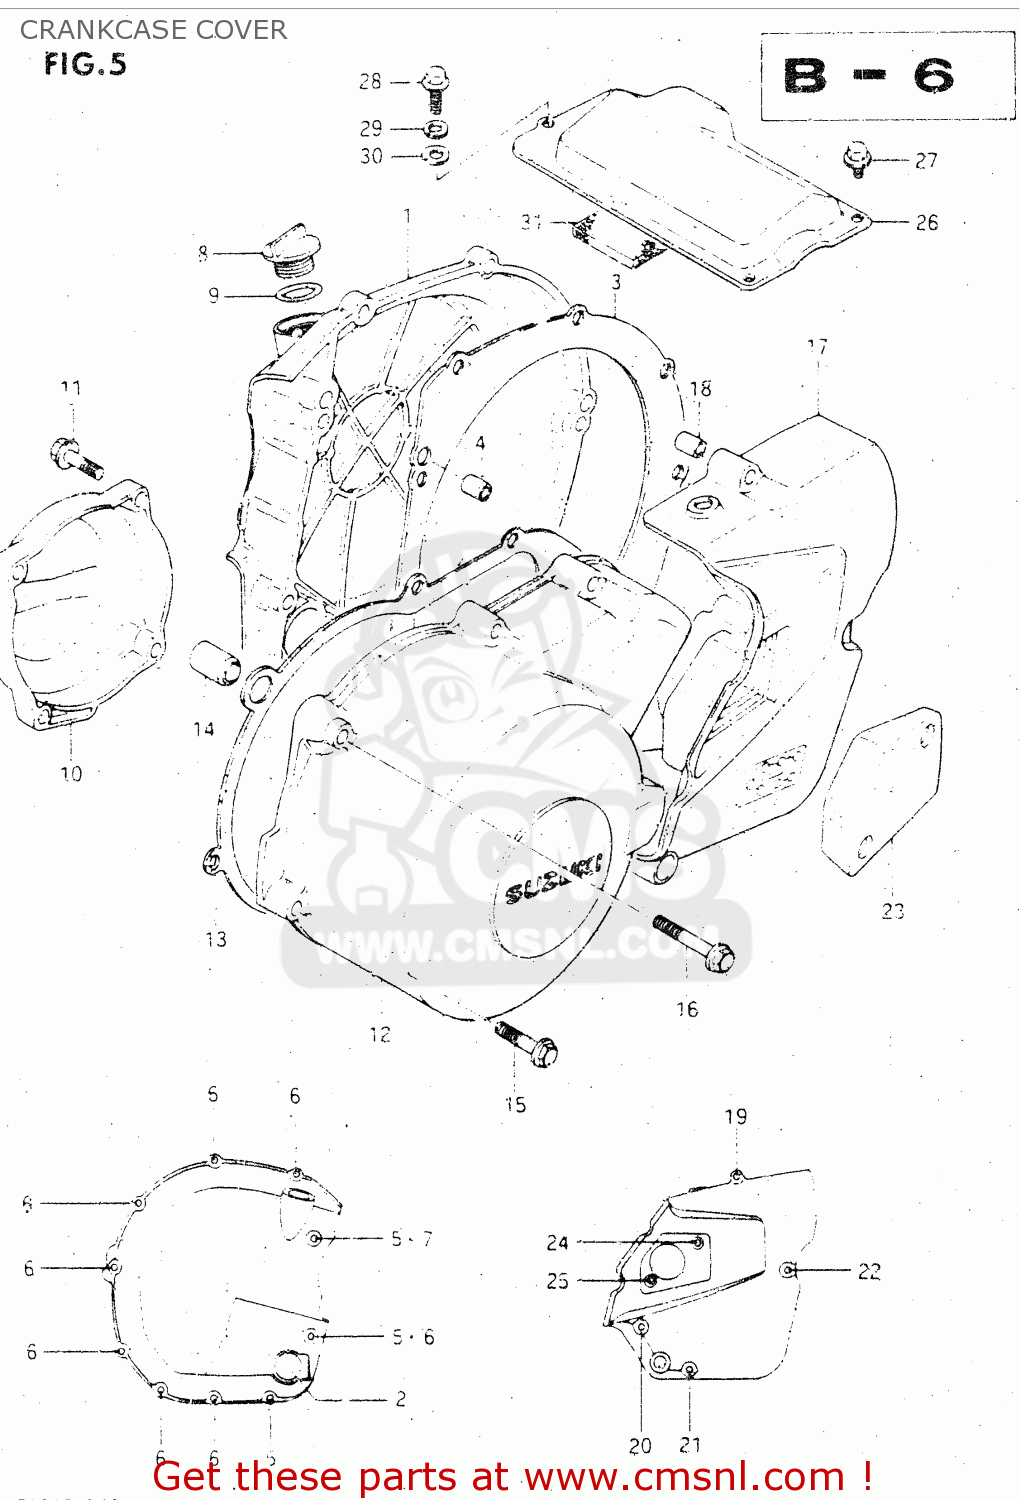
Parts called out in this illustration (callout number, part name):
1	COVER,CLUTCH
2	LENS,OIL LEVEL CHECK
3	GASKET,CLUTCH COVER (MCA)
4	PIN
5	WASHER
6	BOLT 6X25
7	BOLT 6X35
8	PLUG
9	O RING(D:3.1,ID:16.8)
10	COVER,CONTACT BREAKER
11	BOLT 6X25
12	COVER,MAGNETO
13	GASKET,MAGNETO COVER (MCA)
14	PIN (11X20)(SUS)
15	BOLT 6X30
16	BOLT
17	COVER,ENGINE SPROCKET
18	PIN
19	BOLT 6X40
20	BOLT (6X55)
21	BOLT 6X50
22	BOLT 6X80
23	CAP,CLUTCH RELEASE ADJUST
24	SCREW
25	SCREW
26	COVER,STARTER MOTOR
27	BOLT
28	BOLT
29	WASHER,LOCK
30	WASHER
31	DAMPER,STARTER MOTOR CLUTCH
